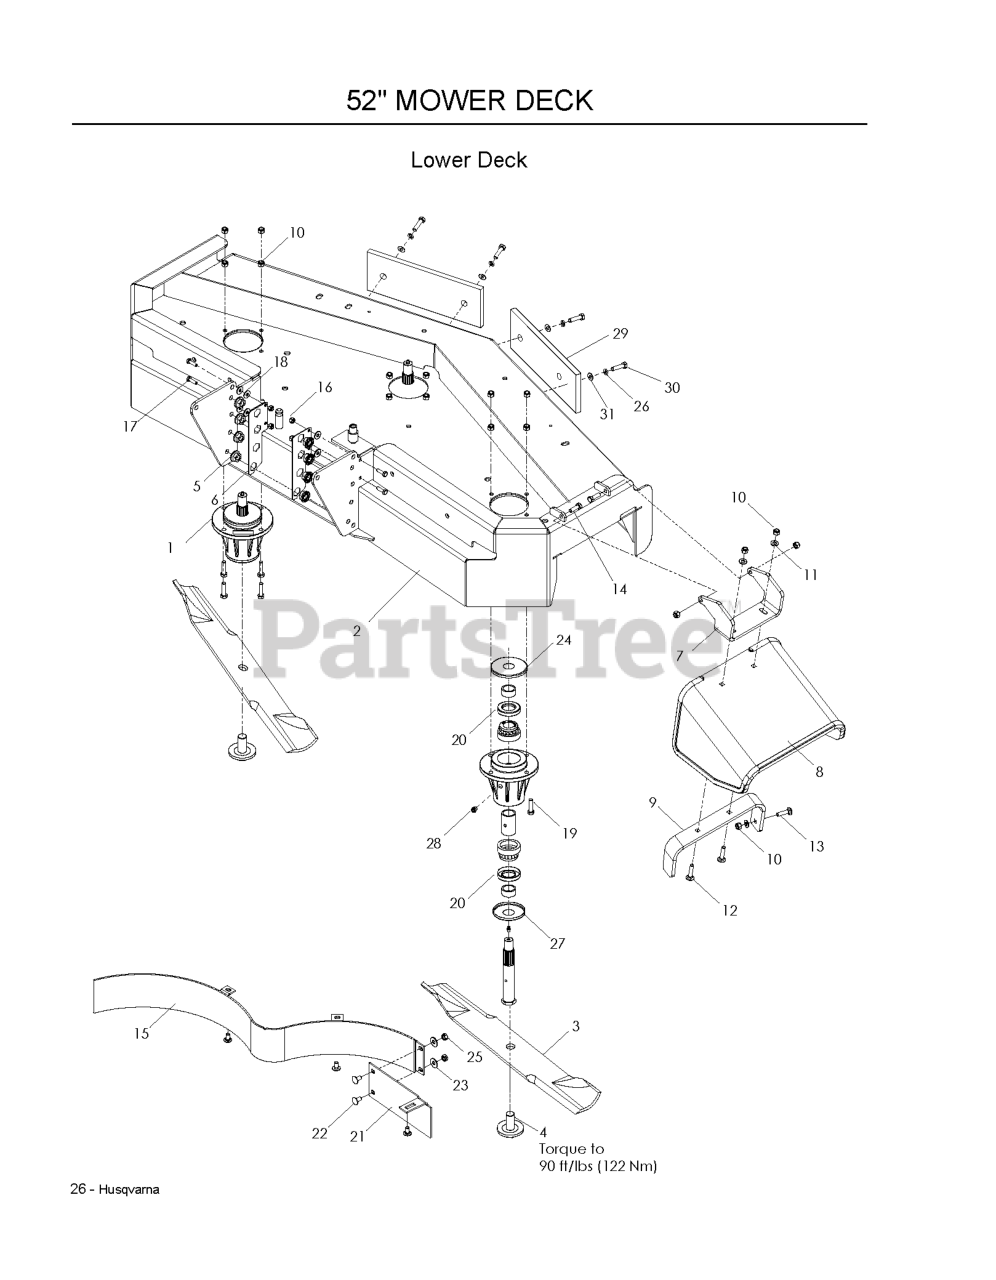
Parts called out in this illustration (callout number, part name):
1	HOUSING ASM, 72
2	DECK SVC W/DECALS WH5218
3	BLADE OEM 18"
4	BLADE BOLT/WASHER
5	NUT FLANGE 1/2-13 GR 5
6	PLATE NUT - PAINTED
7	HINGE CHUTE - BLACK
8	CHUTE, RUBBER DISCHARGE WB
9	BRKT, REINF-CHUTE WB
10	NUT 5/16 NYLOC
11	FLAT WASHER 5/16 SAE
12	RHSNB 5/16-18 X 1-1/2 GR 5 ZD
13	BOLT, CARRIAGE 5/16X1-1/4
14	HCS 5/16C X 1
15	MAIN BAFFLE 52"
16	NUT.1/4-20.HEX.NYLOC.ZD
17	HCS 1/4-20X7/8 GR5
18	WASHER 1/4 FLAT
19	HCS 5/16C X 1 1/4
20	SHAFT SEAL
21	CENTER BAFFLE - 52"
22	CARRIAGE BOLT 5/16C X 5/8"
23	WASHER 5/16 FLAT
24	TOP DUST CAP
25	NUT 5/16C CENTERLOCK
26	WASHER 1/2" SPLIT LOCK
27	BOTTOM DUST CAP
29	WEIGHT, COUNTER, ORANGE
30	HCS 1/2-13 X 1-1/2 GR 5 ZD
31	WASHER 1/2" FLAT
